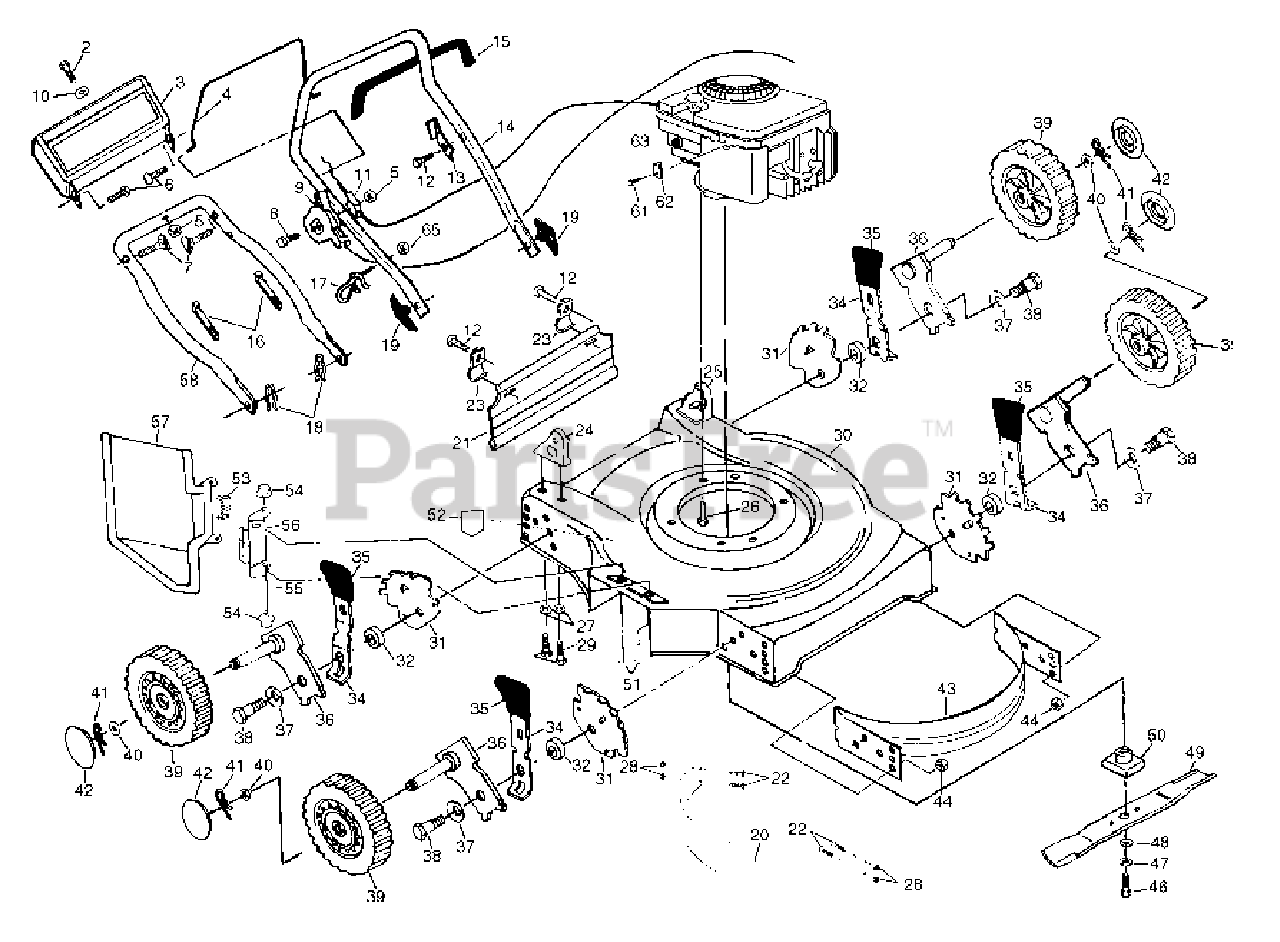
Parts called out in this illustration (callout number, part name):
2	Hex Washer Head Screw 1/4-20 x 1-1/2
3	Trim Plate
4	Control Bar
5	Locknut 1/4-20
6	Self-tapping Screw #10-24 x 5/8
7	Handle Bolt 5/16-18 x 1-3/4
8	Hex Washer Head Screw 1/4-20 x 2.12
9	Throttle Control
11	Engine Zone Control Cable
12	Hex Washer Head Screw #10-2
13	Up-Stop Bracket
14	Upper Handle
15	Handle Grip
16	Wire Tie
17	Rope Guide
18	Hairpin Cotter
19	Handle Knob
20	Closeout Plate
21	Rear Skirt
22	Machine Screw
23	Rear Skirt Bracket
24	Handle Bracket Assembly (Right)
25	Handle Bracket Assembly (Left)
26	Thread Rolling Screw 3/8-16 x 1
29	Screw 5/16-18
30	Lawn Mower Housing
31	Wheel Adjusting Bracket
32	Spacer
34	Selector Spring
35	Selector Knob
36	Axle Arm Assembly
37	Belleville Washer
38	Shoulder Bolt 3/8-16
39	Wheel Assembly
41	Retainer Clip
43	Front Baffle
44	Locknut 3/8-16
46	Hex Head Screw 3/8-24 x 1-3/8 Gr. 8
47	Helical Lockwasher 3/8
48	Hardened Washer
49	20" Blade
50	Blade Adapter
51	Screw
52	Danger Decal
53	Torsion Spring
55	Hinge Rod
56	Housing Bracket
57	Discharge Guard
58	Lower Handle
61	Thread Rolling Screw #10-32 x 5/8
62	Cable Clamp
65	Keps Locknut 1/4-20
